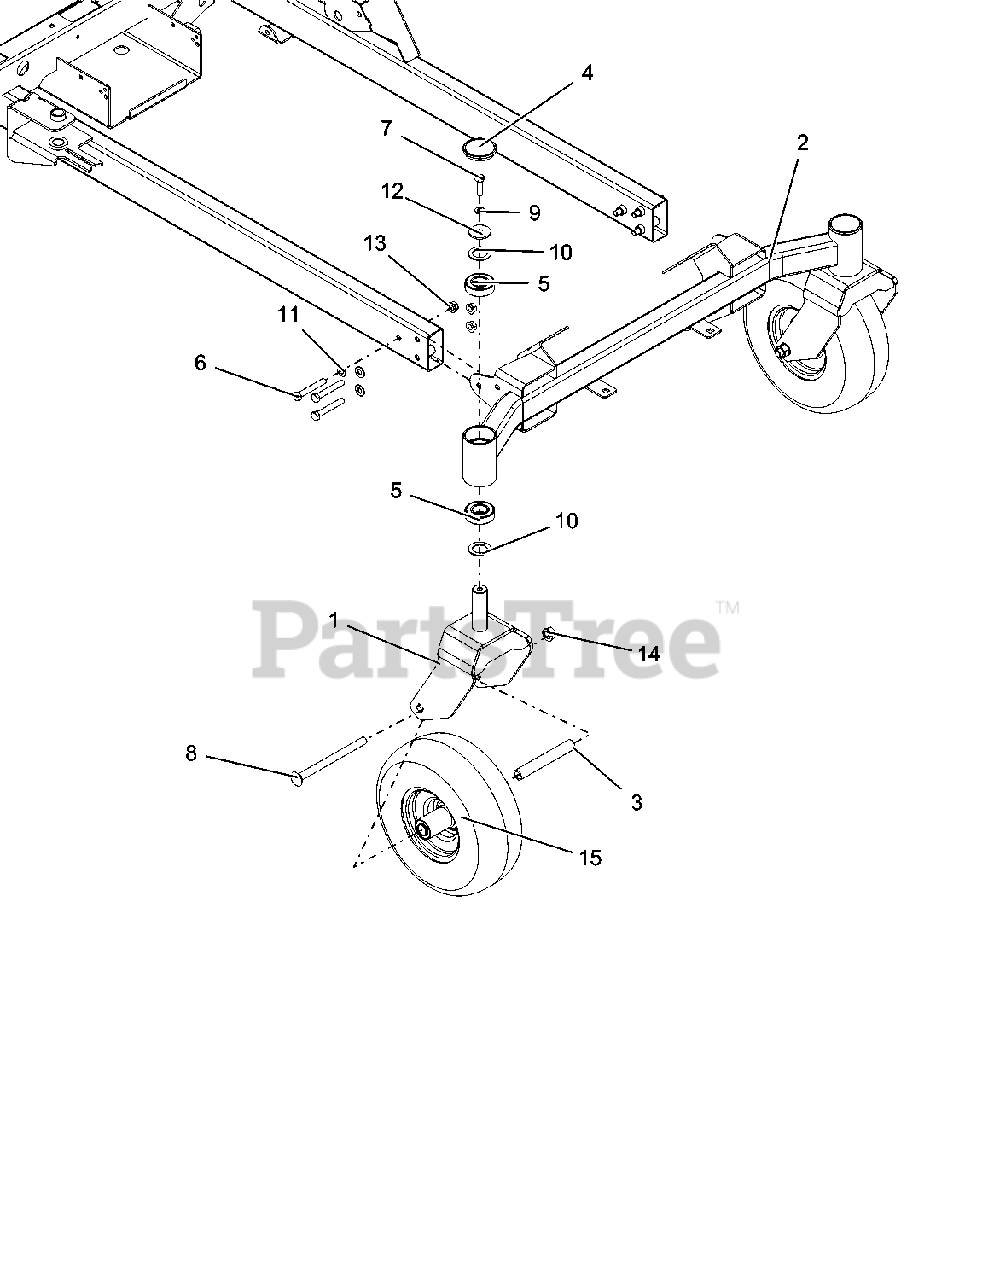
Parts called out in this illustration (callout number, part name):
1	WMT, CASTER FORK
2	WLDMT, AXLE FRONT
3	SPACER, ROLLED WHEEL
4	CAP, DUST
5	BRG,BALL 1.00X2.00X.563(1641)
6	BLT-HEX .38-16X2.50 GR8 YWZC
7	@BLT-HEX .38-16X1.25 GR5 YWZC
8	BLT-RDHDSQNK .50-13X6.50 GR5 Y
9	@WSHR-LK .38X.094 REG YWZC
10	WSHR-HRD-THRS 1.007X1.542X.062
11	WSHR-HDND .406X.812X.055
12	WSHR-FL-STL .380X1.50X.125YWZC
13	NUT-LK-TOP-FLG .38-16 GRG YWZC
14	@NUT-LK-TOP-FLG .50-13 YWZC
15	ASM, WHL/TIRE 11X4.00-5
